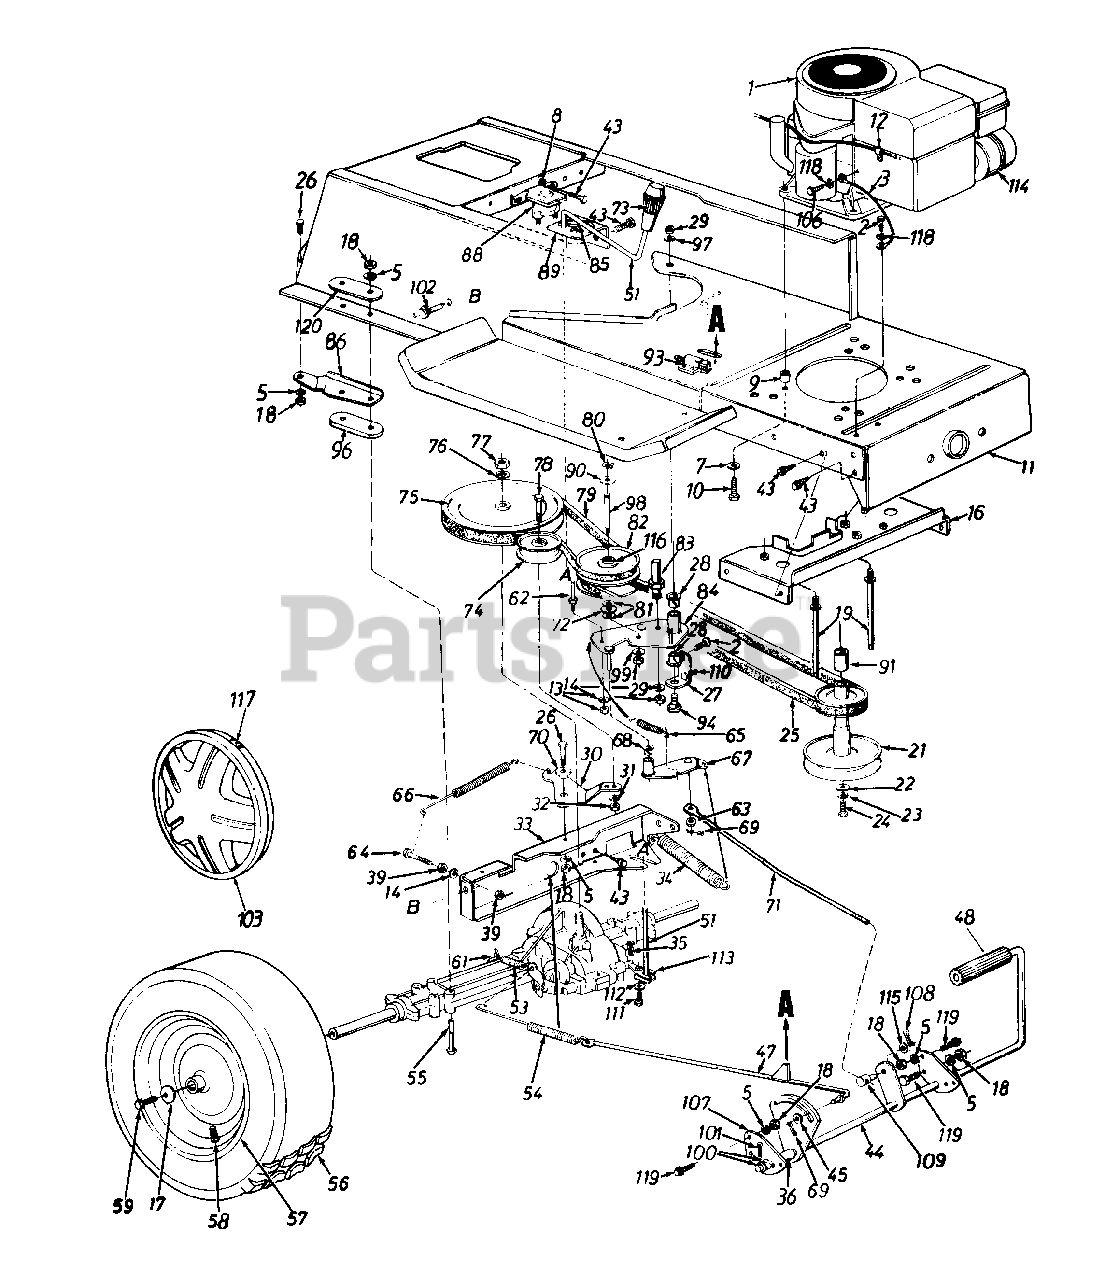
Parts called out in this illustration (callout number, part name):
1	Engine
2	Hex Wash. AB-Tap Scr. 5/16" x .75"
3	Electric Ground Wire
5	L-Wash. 5/16" I.D.
7	Fl-Wash. .406" I.D. x 1.25"
8	Ext. L-Wash. 1/4" I.D.
9	Spacer
10	Hex Tap Scr. 3/8-16 x 1.5" Lg.
13	Hex Nut 1/4-20 Thd.
14	L-Wash. 1/4" I.D.
18	Hex Nut 5/16-18 Thd.
19	Belt Guard Stud 3.6" Lg.
21	Engine Pulley
22	Fl-Wash 7/16" I.D. x 1.25"
23	L-Wash. 7/16" I.D.
24	Hex Bolt 7/16-20 x 1.50" Lg.
25	Variable-Speed Belt
26	Hex Bolt 5/16-18 x .75" Lg.
27	Bearing Shaft Bracket Ass'y
28	Flanged Nyliner Brg. .63" I.D. x .6" Lg.
29	Hex Nut 3/8-24 Thd.
31	L-Wash. 3/8" I.D.
32	Hex Nut 3/8-24 Thd.
35	Inter. Cott-Pin
36	Spacer .63" I.D.
39	Hex Nut 1/4-28 Thd.
43	Hex Wash. Hd. S-Tap Scr. 1/4-20 x .50" Lg.
47	Brake Rod Ass'y.
48	Foot Pad
51	Shift Lever Ass'y.
53	Ext. Spring .38" O.D. x 2.5"
54	Ext. Spring 7.08"
55	Hex Bolt 5/16-18 x 3.5" Lg.
58	Air Valve
59	Hex Bolt 5/16-24 x .75" Lg.
61	Brake Return Spring Anchor
62	Belt Guard Pin 1/4-20 Thd.
63	Fl-Wash. .34" I.D. 2 .68" O.D.
64	Hex Bolt 1/4-28 x 1.25" Lg.
65	Ext. Spring
66	Ext. Spring .62" O.D. x 6.12"
69	Cotter Pin 3/32" Dia.
70	Shoulder Spacer .27" Lg.
71	Speed Control Link
72	Truss Bearing .56 Dia. x 1.25"
73	Shift Knob
74	Fl-Idler Pulley 3.25" x .75"
75	"V"-Pulley
76	Bell-Wash. .56" I.D. x 1.125"
77	Hex Jam Nut 9/16-18 Thd.
78	Hex Bolt 3/8-24 x 1.75" Lg.
79	Variable Speed Belt
80	Snap Ring .56" Dia.
81	Fl-Wash.
82	Variable Speed Pulley Ass'y. 5" O.D.
83	Belt Keeper 3" Lg.
90	Teflon Washer .565" I.D.
91	Spacer 1" I.D. x 1.25" Lg.
93	Safety Switch (Clutch)
94	Shld. Bolt 3/8-24 x 3.12" Lg.
96	Transaxle Spacer
97	Bell-Wash. .38" I.D. x .88"
98	Shaft .56" Dia. x 3.875" Lg.
99	Bell-Wash. .39" I.D. x 1.12"
100	Fl-Wash. .64" I.D. x .94"
101	Cotter Pin 1/8" Dia. x 1.25"
102	Hex Wash. Hd. Scr. 5/16-18 x .62" Lg.
103	Hub Cap (Gray)
106	Pan Hd. Mach. Scr. 5/16-18 x .75" Lg.
109	Ferrule
110	Hex Bolt 5/16-18 x 1.0" Lg. (Gr. 5)
111	Hex Bolt 1/4-28 x .50" Lg.
112	Bell-Wash. .265" I.D. x .75"
113	Shift Lever Link Ass'y.
114	Muffler
115	Fl-Wash. .385" I.D. x .62"
116	Needle Brgs.
117	Spring Clip
118	External L-Wash. 5/16" I.D.
119	Hex TT-Tap Scr. 5/16-18 x .75"
